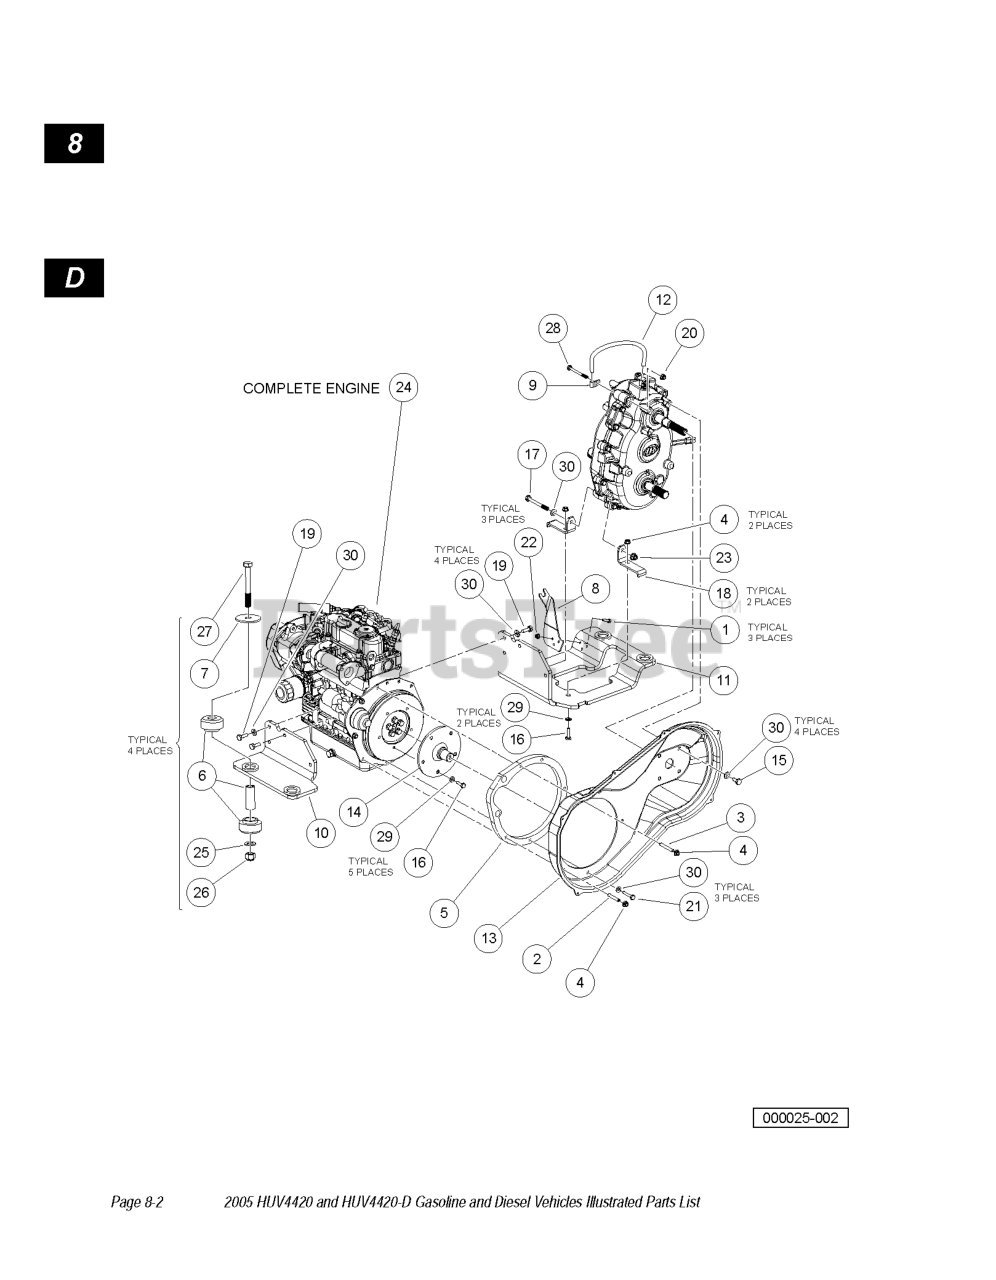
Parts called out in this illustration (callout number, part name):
2	STUD, M8-1.25 X 50MM 2-ENDED
3	STUD, M8-1.25 X 60MM 2-ENDED
4	NUT FLG, M8 X 1.25 MECH DEF
5	SPACER, ENGINE, DIESEL
6	ISOLATOR, RING AND BUSHING
7	WASHER, SNUBBING, RING N BUSH
8	BRACKET, FNR TRANS CABLE
9	P-CLAMP, INSULATED .312 IN
10	Plate, Engine Mounting, Weld, Left-Hand
11	PLATE, ENG MTG, WELD, RH
12	HOSE, VENT, TRANSMISSION
13	COVER, CVT INNER, DIESEL
14	SHAFT, CVT ADAPTER
15	BOLT, M10 X 1.5 X 20 LOCTITE
16	BOLT, M8 X 1.25 X 25 LOCTITE
17	BOLT, M10 X 1.5 X 100 LOCTITE
18	BRACKET, TRANSMISSION MTG
19	BOLT, M10 X 1.25 X 25 LOCTITE
20	LOCK NUT, FLG M8 X 1.25 NYLON
21	BOLT, M8X1.25X40 LOCTITE
22	NUT FLG, M6 X 1.0 NYLON
23	NUT FLG M10 X 1.5 NYLON
24	ENGINE, KUBOTA, D722, CB, 60A
25	WASHER, M12 HARD
27	BOLT, M12 X 1.75 X 90
28	BOLT, M8 X 1.25 X 80
29	WASHER, M8 HARD
30	WASHER, M10 HARD
